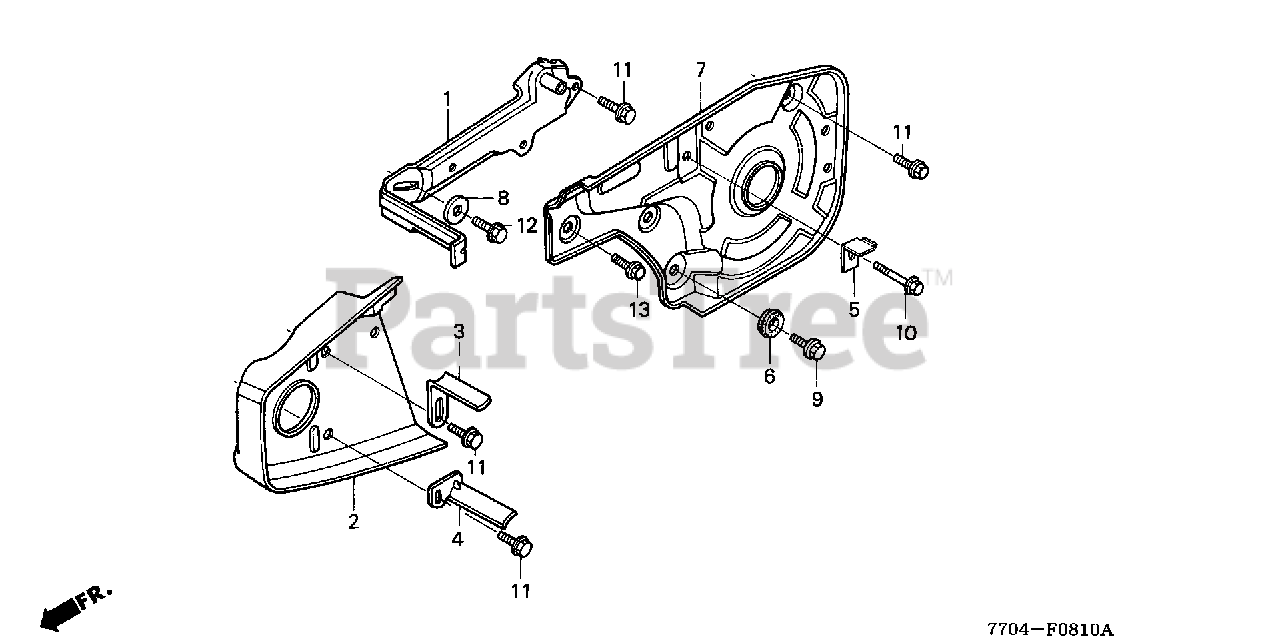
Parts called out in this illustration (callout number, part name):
1	STAY, ENGINE
2	PLATE, ENGINE ADJUSTING
3	STOPPER A, BELT
4	STOPPER, BELT
5	STOPPER C, BELT
6	GROMMET, WIRE HARNESS
7	STAY, BELT COVER
8	WASHER (8MM)
9	BOLT-WASHER (6X16)
10	BOLT, FLANGE (6X32)
11	BOLT, FLANGE (8X16)
12	BOLT, FLANGE (8X20)
13	BOLT, FLANGE (6X12)
